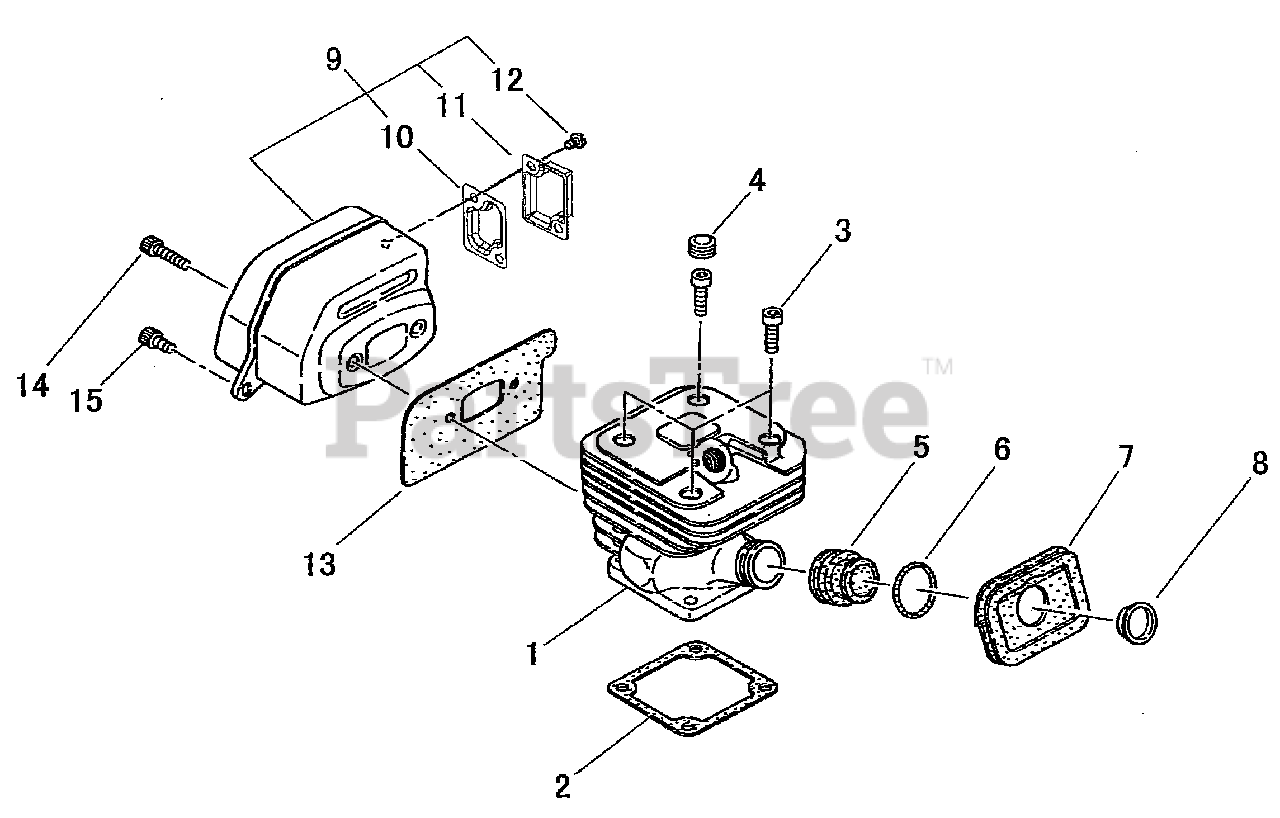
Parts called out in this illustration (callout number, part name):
1	CYLINDER
2	GASKET, CYLINDER
3	BOLT M5×18
4	PLUG
5	BOOT
6	SPRING
7	SEAL
8	SLEEVE
9	MUFFLER ASSY
10	SCREEN, SPARK ARRESTER
11	COVER, SPARK ARRESTER
12	SCREW M4×6
13	GASKET
14	BOLT M5×18
15	BOLT
